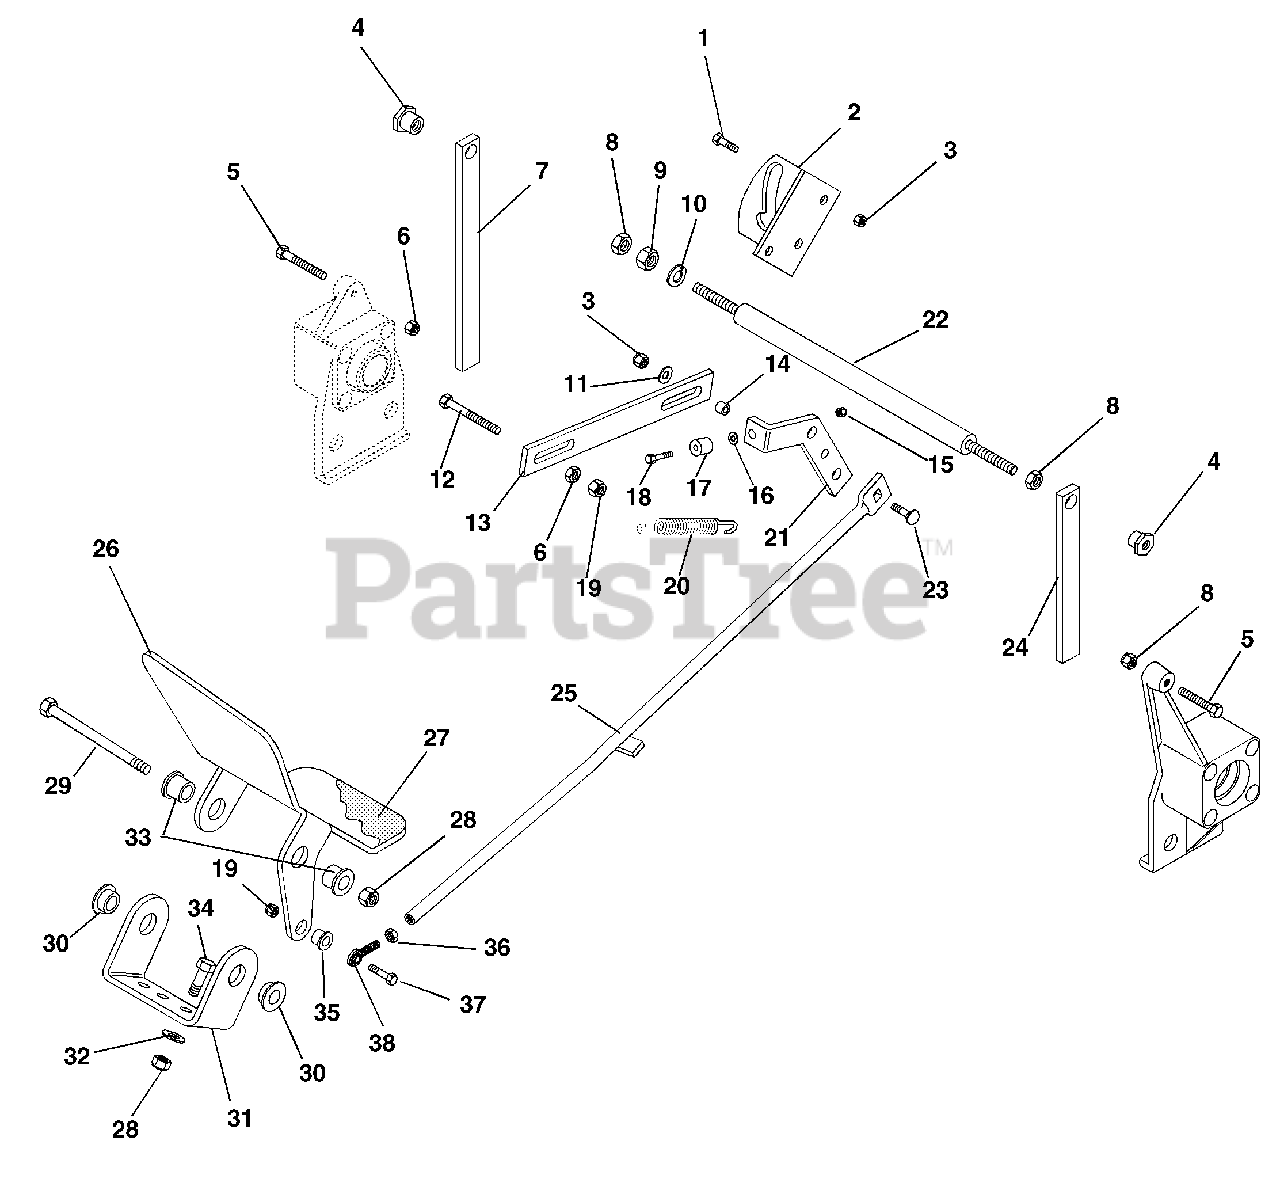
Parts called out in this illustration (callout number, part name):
1	Bolt-Hex .31-18 x 1.00 Grade 5
2	Weldment, Forward-Reverse Actuating
3	Nut-Locking-Center .31-18
4	Bushing-Flange .50 x .88 x .70 Steel
5	Bolt-Hex .38-16 x 2.50
6	Nut-Hex .38-16
7	Spring, Reverse Clutch
8	Nut-Jam .50-13
9	Nut-Hex .50-13
10	Washer-Locking .50 x .151
11	Washer-Flat-Steel .38 x .88 x .083
12	Bolt-Hex .38-16 x 3.00 Grade 5
13	Strap, Neutral Detent
14	Bushing, Sleeve .33 x .50 x .50l Steel
15	Nut-Locking-Center .25-28
16	Washer-Flat-Steel .28 x .62 x .065
17	Roller-Clutch Cam .25 x .75 x .56
18	Bolt-Hex .25-28 x 1.38
19	Nut-Locking-Center .38-16
20	Spring-Tension .06 x .50 x 3.10
21	Arm, Forward-Reverse Clutch Roll
22	Rod, Forward-Reverse Slide
23	Bolt-Round Head Square Neck .31-18 x 1.25 Grade 5
24	Spring, Forward-Reverse Clutch
25	Weldment,Forward-Reverse Rod
26	Pedal, Foot Clutch
27	Pad, Foot Clutch Pedal
28	Nut-Locking-Center .50-13
29	Bolt-Hex .50-13 x 6.50 Grade 5
30	Bushing-Flange .76 x 1.00 x .58 x 1.48 Nylon
31	Bracket, Clutch Pedal Pivot
32	Washer-Flat-Steel .56 x 1.38 x .11
33	Bushing-Flange .52 x .75 x .75 x 1.00
34	Bolt-Hex .50-13 x 1.25 Grade 5
35	Bushing-Flange .32 x .62 x .312
36	Nut-Jam .38-24
37	Bolt-Hex .38-16 x 1.25 Grade 5
38	Rod End, .38 Right Hand
